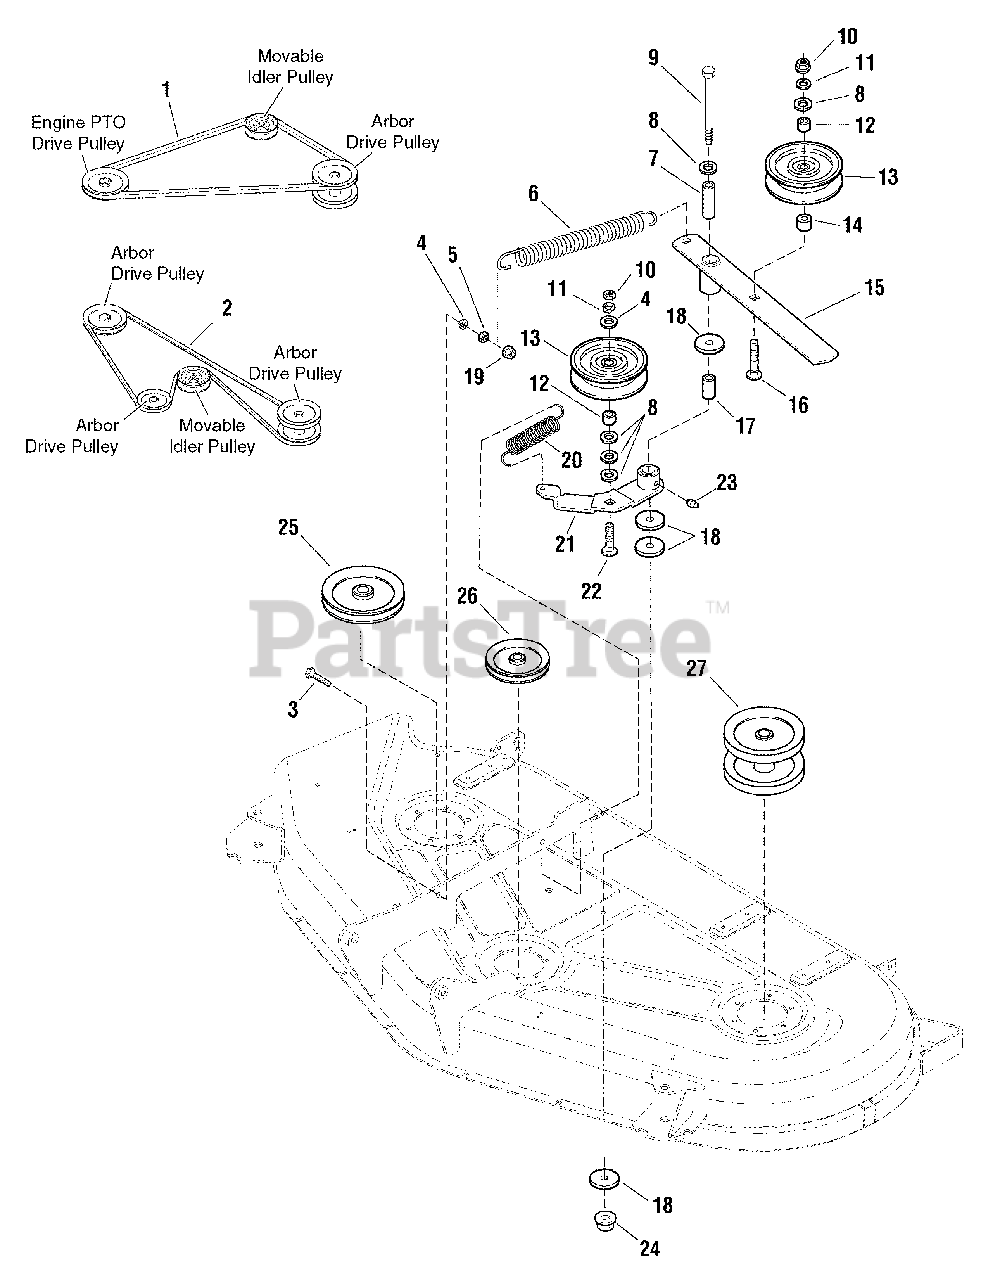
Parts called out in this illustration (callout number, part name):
1	V-BELT, Engine PTO
2	V-BELT, 54 Mower Deck
3	CAPSCREW, Hex Head, 5/16-18 x 1-1/4
4	WASHER, Lock, 5/16
5	NUT, Hex, 5/16-18
7	SPACER, 25/64 x 5/8 x 1-55/64
8	WASHER, 3/8
9	CAPSCREW, Hex Head, 3/8-16 x 4-1/2
10	NUT, Hex, 3/8-16
11	WASHER, Lock, 3/8
12	HUB, 25/64 x 3/4 x 63/64, Powder Metal
13	PULLEY, Idler (Includes Ref. No. 12)
15	ASSEMBLY, Lever
16	CARRIAGE BOLT, 3/8-16 x 2
18	WASHER, 3/8
19	NUT, Hex Centerlock, 5/16-18, Black
20	SPRING, Extension, 4" Long
21	LEVER ASSEMBLY, (Includes Ref. No. 23)
22	CARRIAGE BOLT, 3/8-16 x 1-1/2
23	FITTING, Lube
24	NUT, Hex Flange, 3/8-16
25	PULLEY ASSEMBLY, R.H.
26	PULLEY ASSEMBLY, Center
27	PULLEY ASSEMBLY, L.H.
